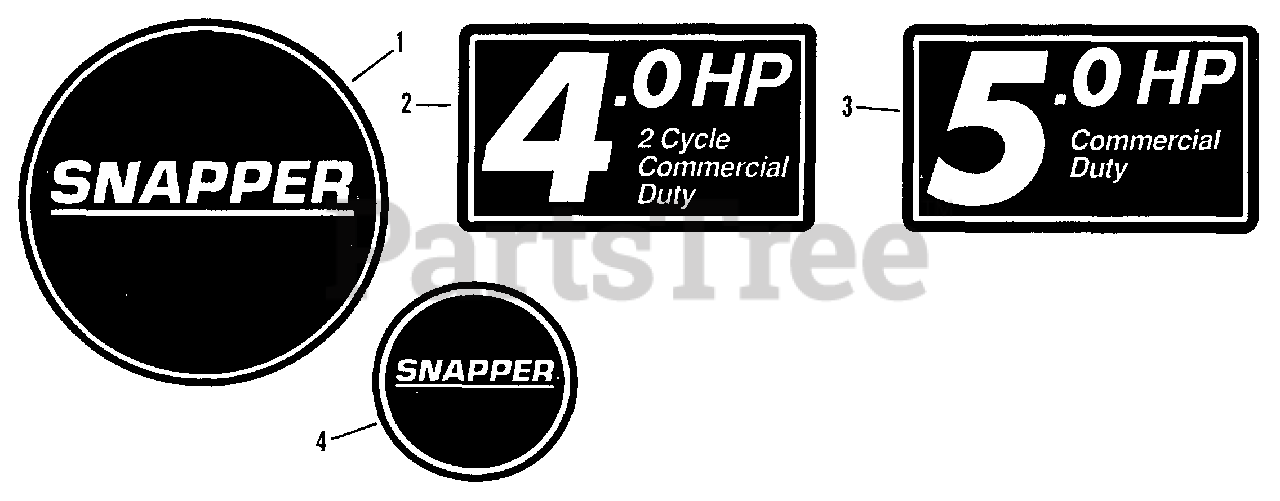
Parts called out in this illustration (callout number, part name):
1	DECAL, Recoil Housing (3.35 O.D.)
2	DECAL, 4HP 2-Cycle
3	DECAL, 5HP
4	DECAL, Recoil Housing (1.8 O.D.)
